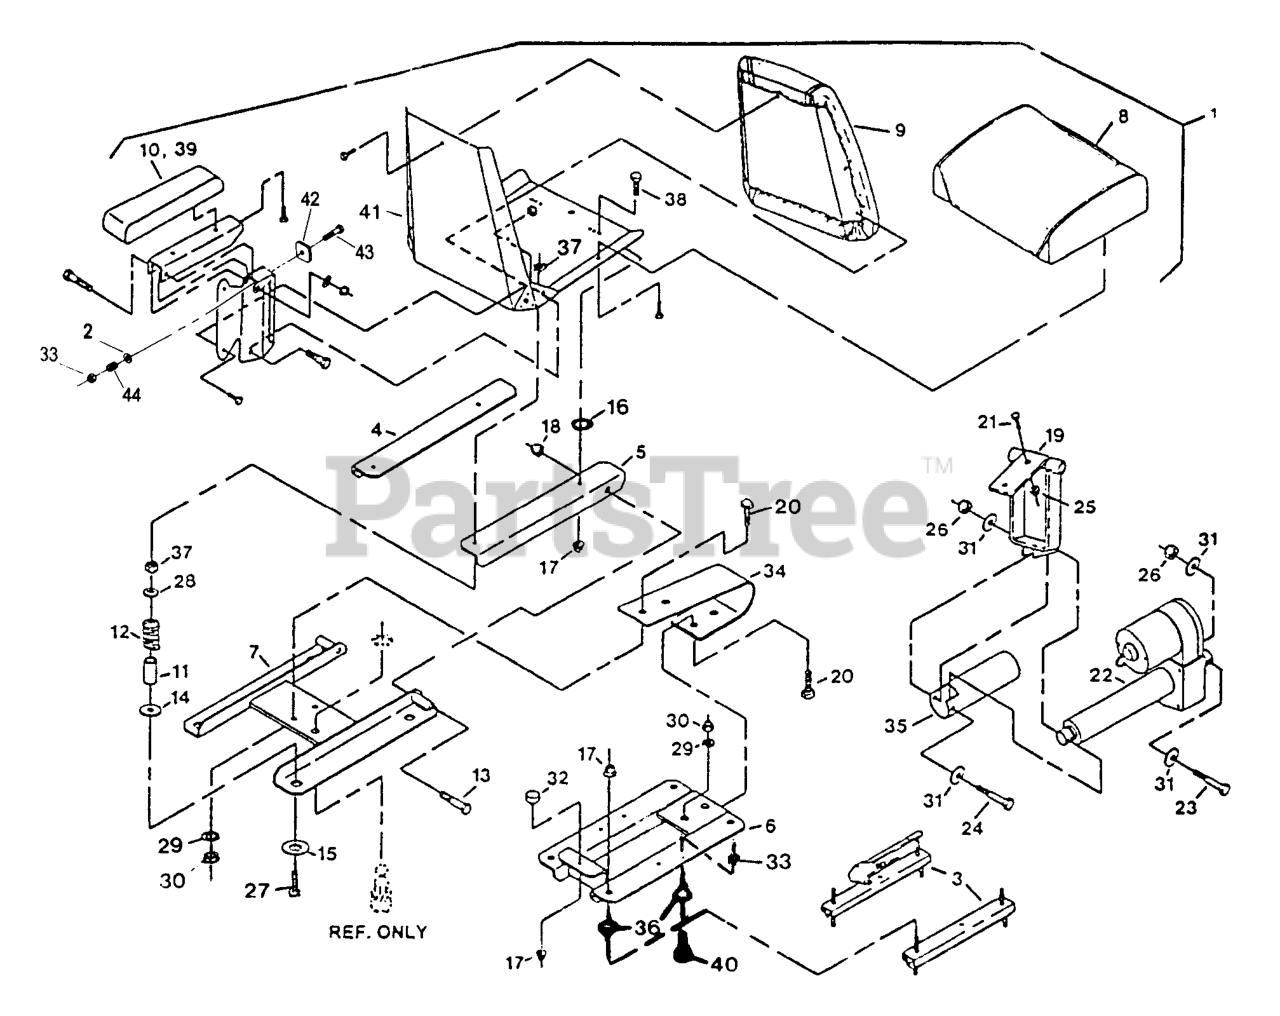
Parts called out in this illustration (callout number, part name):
2	WASHER-PLAIN
4	RAIL,SEAT LH
5	RAIL,SEAT RH
10	CUSHION,ARMREST RH
11	BUSHING,SPRING GUIDE
12	SPRING-INDICATOR, REVERSE
13	SCREW-HH
14	SCREW-HH
16	WASHER-FLAT
18	NUT-LOCK, NI
20	SCREW-HH
21	SCREW-HH
23	SCREW-HH
24	SCREW-HH
25	NUT-HHF, WHIZ
26	NUT-LOCK
27	BOLT,TAP HH
28	WASHER-FLAT
29	WASHER-LOCK
30	NUT-HH
31	WASHER-FLAT
32	BUMPER-RUBBER
33	NUT-LOCK, NI
35	GUARD,ACTUATOR
36	SPACER-TRACK
37	NUT-HEX
39	CUSHION,ARMREST LH
40	SCREW-PPH
41	FRAME-SEAT
42	TAB,ARMREST ADJUSTMENT
43	SCREW-HH
44	SPRING-TANK, FUEL
